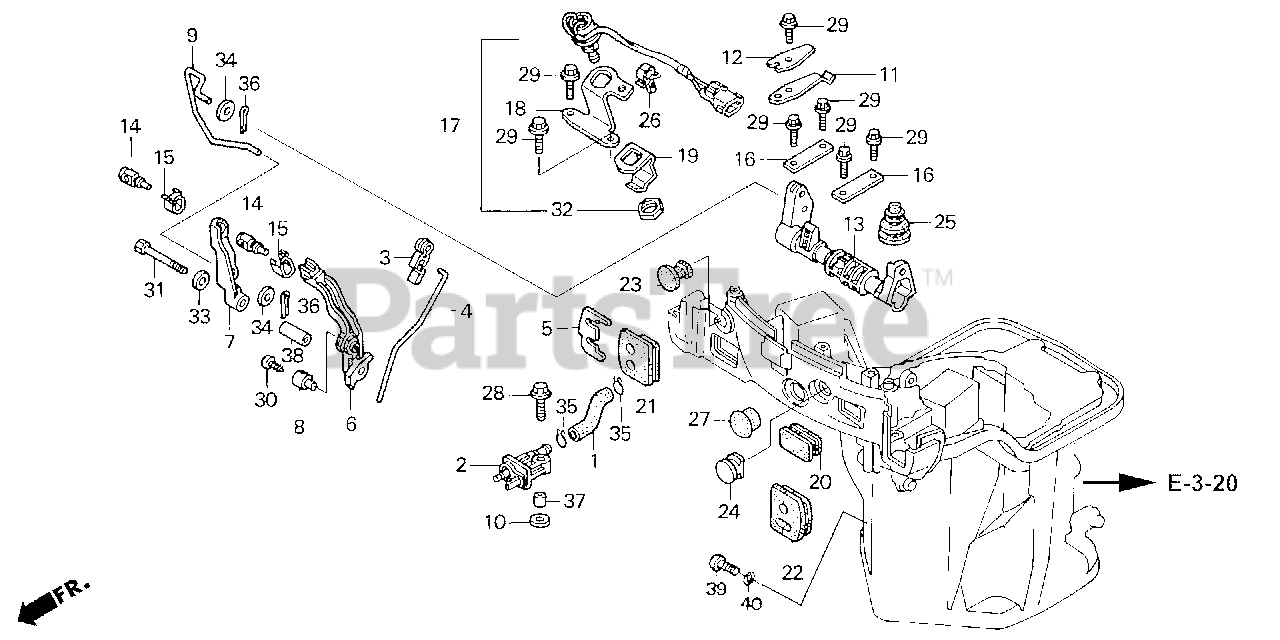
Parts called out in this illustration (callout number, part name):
1	TUBE A, FUEL
2	CONNECTOR ASSY., FUEL (B)
3	LINKAGE, PIVOT
4	ROD, THROTTLE
5	PLATE, REMOTE CONTROL CABLE
6	ARM, THROTTLE REMOTE
7	ARM, SHIFT LINK
8	HOLDER, THROTTLE ROD
9	ROD, SHIFT LINK
10	WASHER, PIVOT
11	SPRING, CLICK
12	SPRING, CLICK ASSIST
13	SHAFT, SHIFT
14	PIVOT, SHIFT
15	PLATE, LOCK
16	PLATE, SHIFT SHAFT
17	SWITCH ASSY., NEUTRAL
18	BRACKET, NEUTRAL SWITCH
19	PLATE, NEUTRAL SWITCH
20	GROMMET G, OIL CASE
21	GROMMET A, OIL CASE
22	GROMMET B, OIL CASE
23	GROMMET F, OIL CASE
24	GROMMET D, OIL CASE
25	GROMMET E, OIL CASE
26	CLIP A, BRAKE PIPE
27	CAP, HANDLE (LOWER)
28	BOLT, FLANGE (6X22) (CT200)
29	BOLT, FLANGE (5X12) (CT200)
30	BOLT, RECESSED (5X8)
31	BOLT, HEX. (6X40)
32	NUT, HEX. (20MM)
33	WASHER (6MM)
34	WASHER, PLAIN (7MM)
35	CLIP, TUBE (B12)
36	PIN, SPLIT (2.0)
37	COLLAR, DISTANCE (6MM)
38	COLLAR, DISTANCE (6X11X27)
